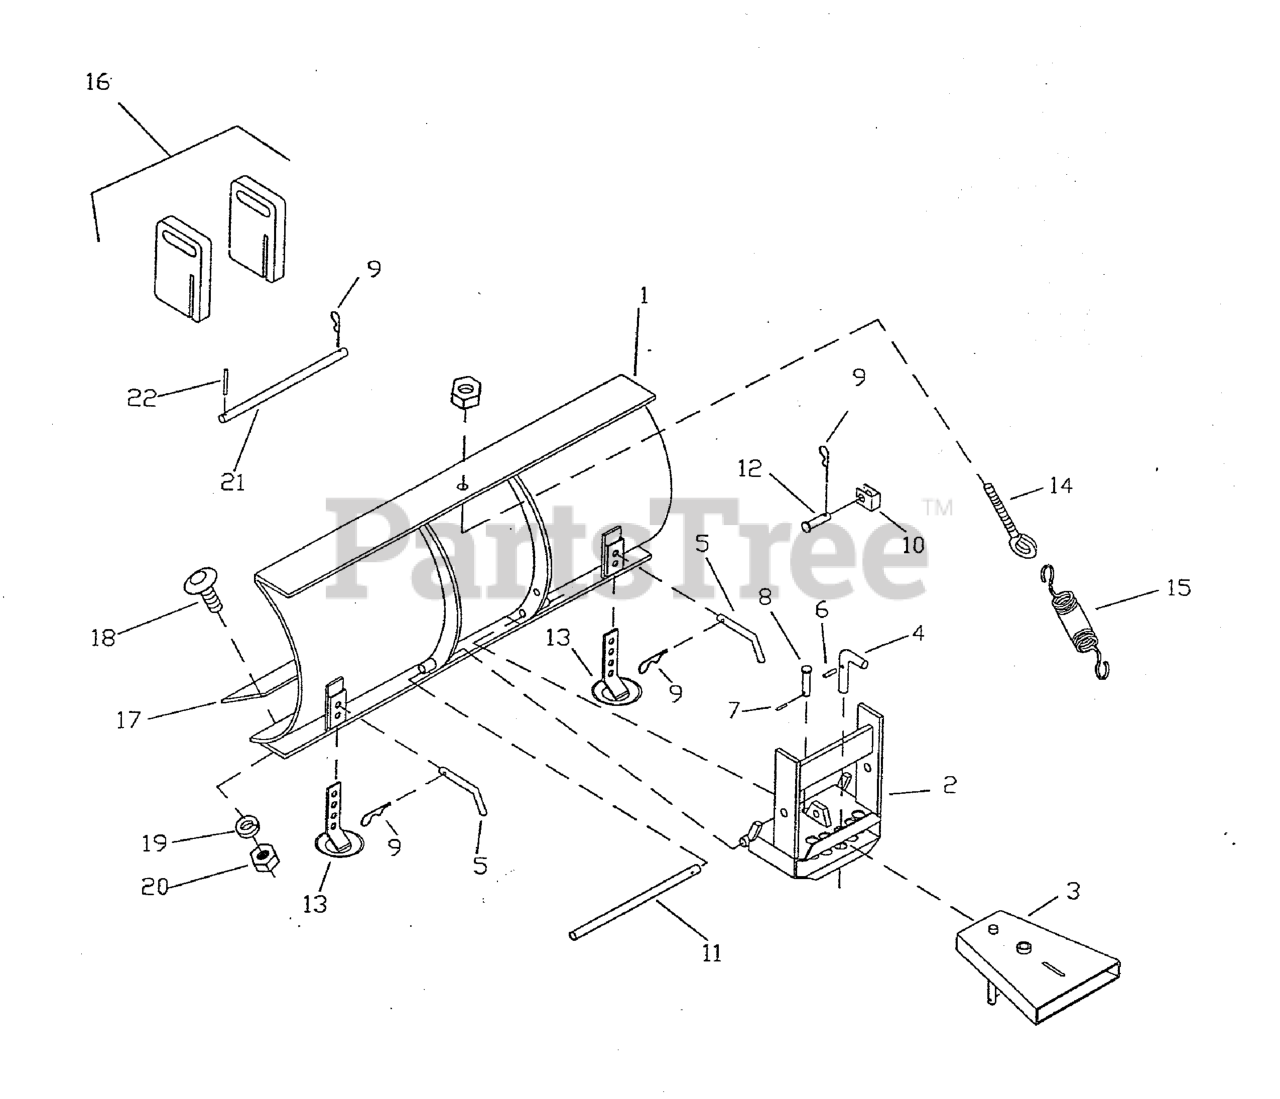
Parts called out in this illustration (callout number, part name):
1	Welded Blade
2	Hitch Box
3	Female Quick Hitch
4	Adjustment Pin
5	Skid Shoe Pin
8	Pivot Pin
10	Trip Spring Lock Out
11	Pin 3/4" Diameter x 17 3/4" Lg.
12	Trip Spring Lock Out Pin
13	Skid Shoe
14	Eye Bolt 5/16" NC x 5" With Hex Nut
16	Counterweight
17	Cutting Edge
20	Hex Nut 3/8" NC
21	Retaining Rod
